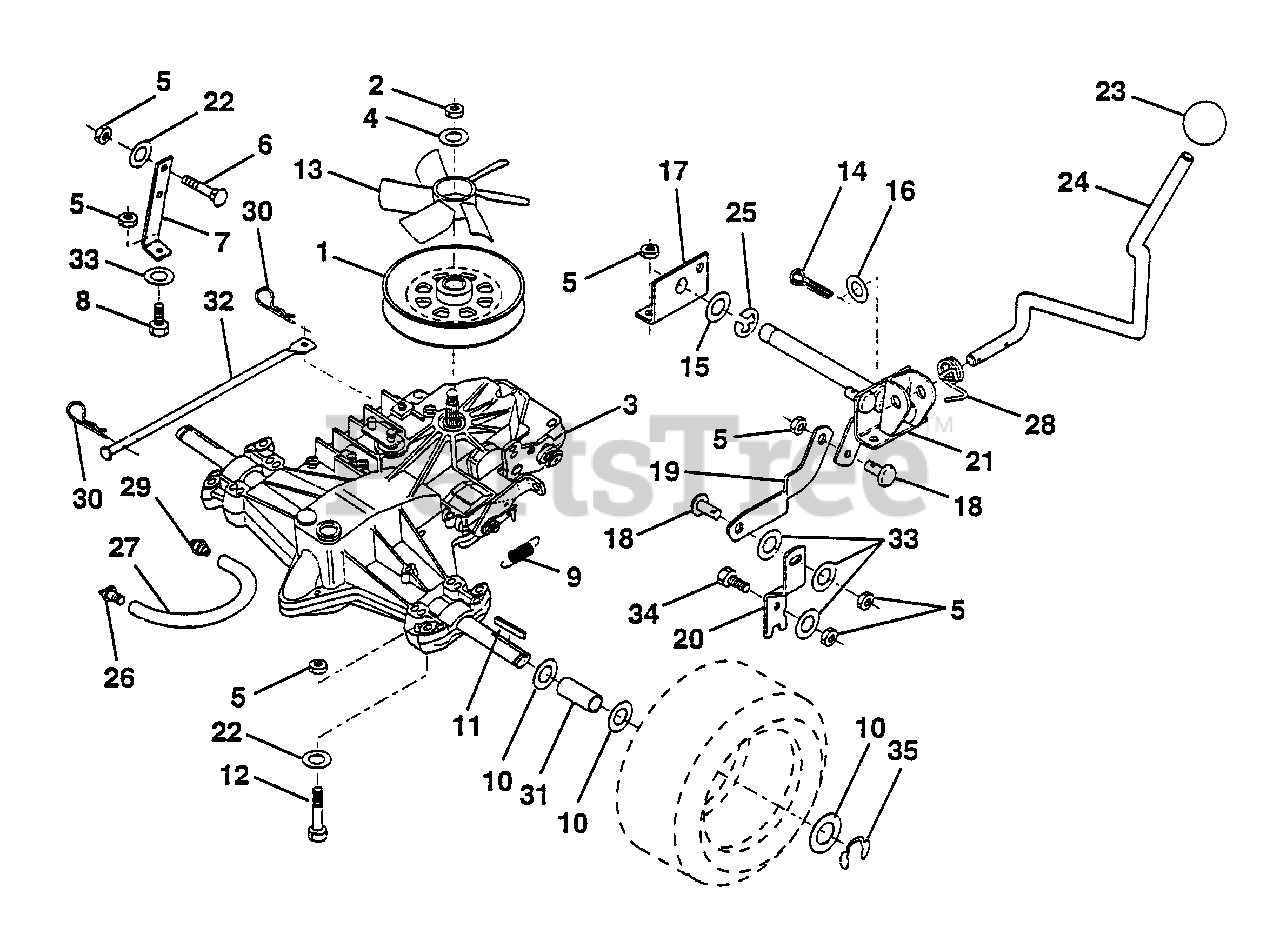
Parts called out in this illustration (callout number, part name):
2	Nut Lock 1/2-20 UNF x 3/4 x 7/16
3	Transaxle, Hydro 0310-0500
4	Washer 17/32 x 1-3/16 x 12 Ga.
5	Nut Lock Hex w/Ins. 5/16-18
6	Bolt, Carriage
7	Strap, Torque
8	Bolt Fin Hex 5/16-18 x 1-1/2
9	Spring Brake
10	Washer 25/32 x 1-1/4 x 16 Gauge
11	Key, Square
12	Bolt, Hex Head 5/16-18 x 2-1/2
13	Fan, Transaxle, Hydro
14	Pin, Cotter 1/8 x 1
15	Washer 21/32 x 1-1/4 x 13 Ga.
16	Washer 17/32 x 3/4 x 16 Ga.
17	Support, Shift Handle
19	Link, Shift
20	Lever, Shift
21	Pivot Shaft Assembly
22	Washer 11/32 x 11/16 x 16 Ga.
23	Knob, Shifter
24	Rod, Shifter
26	Cap, Vent Hose
27	Hose, Vent
28	Spring, Torsion
29	Nipple, Vent Hose
30	Retainer Spring
32	Actuator, Bypass, Hydro
33	Washer 11/32 x 3/4 16 Ga.
34	Bolt Hex Hd. 5/16-18 x 1
